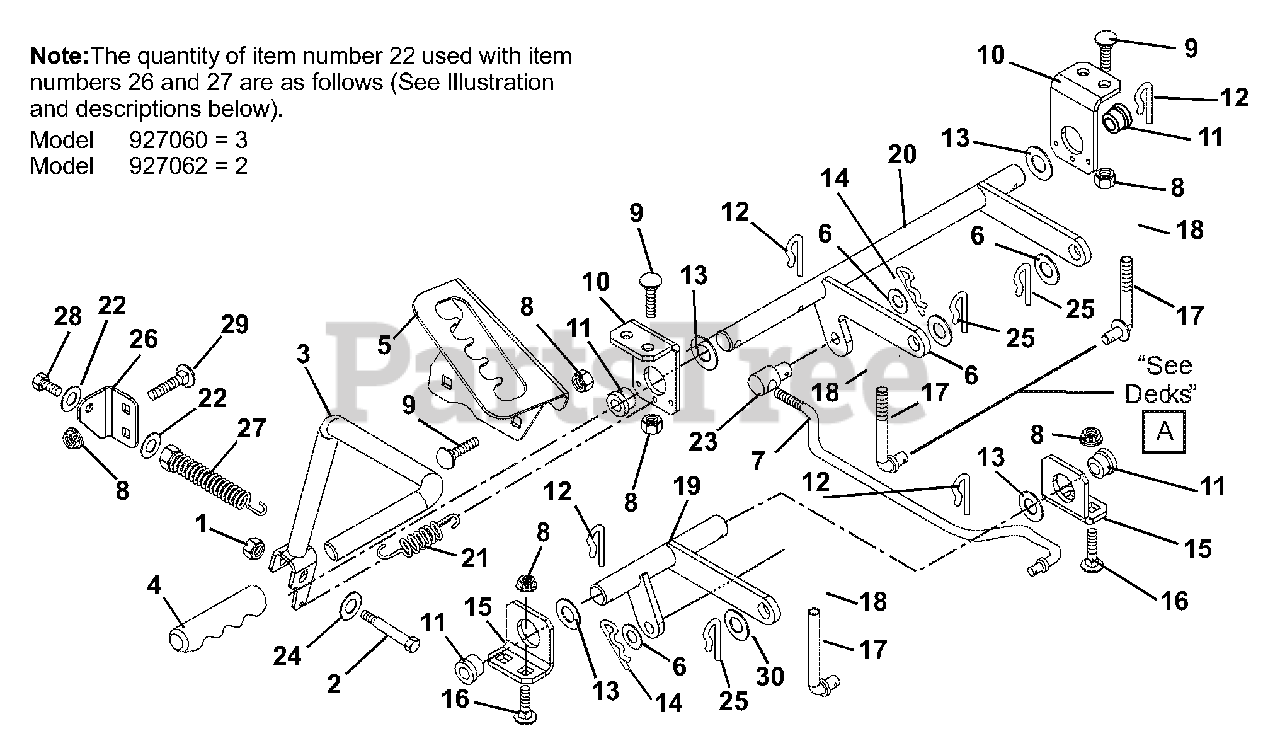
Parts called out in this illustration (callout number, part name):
1	Nut, Locking Top Flange .31-18
2	Bolt, 1.25 Socket Shoulder Plain
3	Weldment, Lift Handle
5	Detent Plate
6	Washer, Flat Steel .511 x 1.44 x .125
7	Rod, Deck Lift
8	Nut, Locking Top Flange .38-16
9	Bolt, Round Head Square Neck .38-16 x .75 Grade 5
10	Bracket, Lift
11	Bushing, Flange .75 x 1.00 x .625 x 1.25
12	Pin, Spring Clip
13	Washer, Flat Steel .563 x 1.38 x .109
14	Pin, Hair #16
15	Bracket, Deck Pivot
16	Bolt, Round Head Square Neck .38-16 x 1.00 Grade 5
17	Rod, Link (060, 062)
18	Trunnion (030)
19	Weldment, Front Lift (060, 062)
20	Weldment, Lift
21	Spring, Extension
22	Washer, Flat Steel .43 x 1.00 x .16 (060)
22	Washer, Flat Steel .43 x 1.00 x .16 (062)
23	Pivot, Rod
24	Washer, Flat Steel .43 x 1.00 x .160
25	Clip, Spring
26	Bracket, Spring Anchor
27	Spring, Tension .195 x 1.15 x 5.50
28	Bolt-Hex .38-16 x 1.50 Grade 5
29	Bolt, Round Head Square Neck .38-16 x .75 Grade 5
30	Washer, Flat Steel .563 x 1.38 x .109
